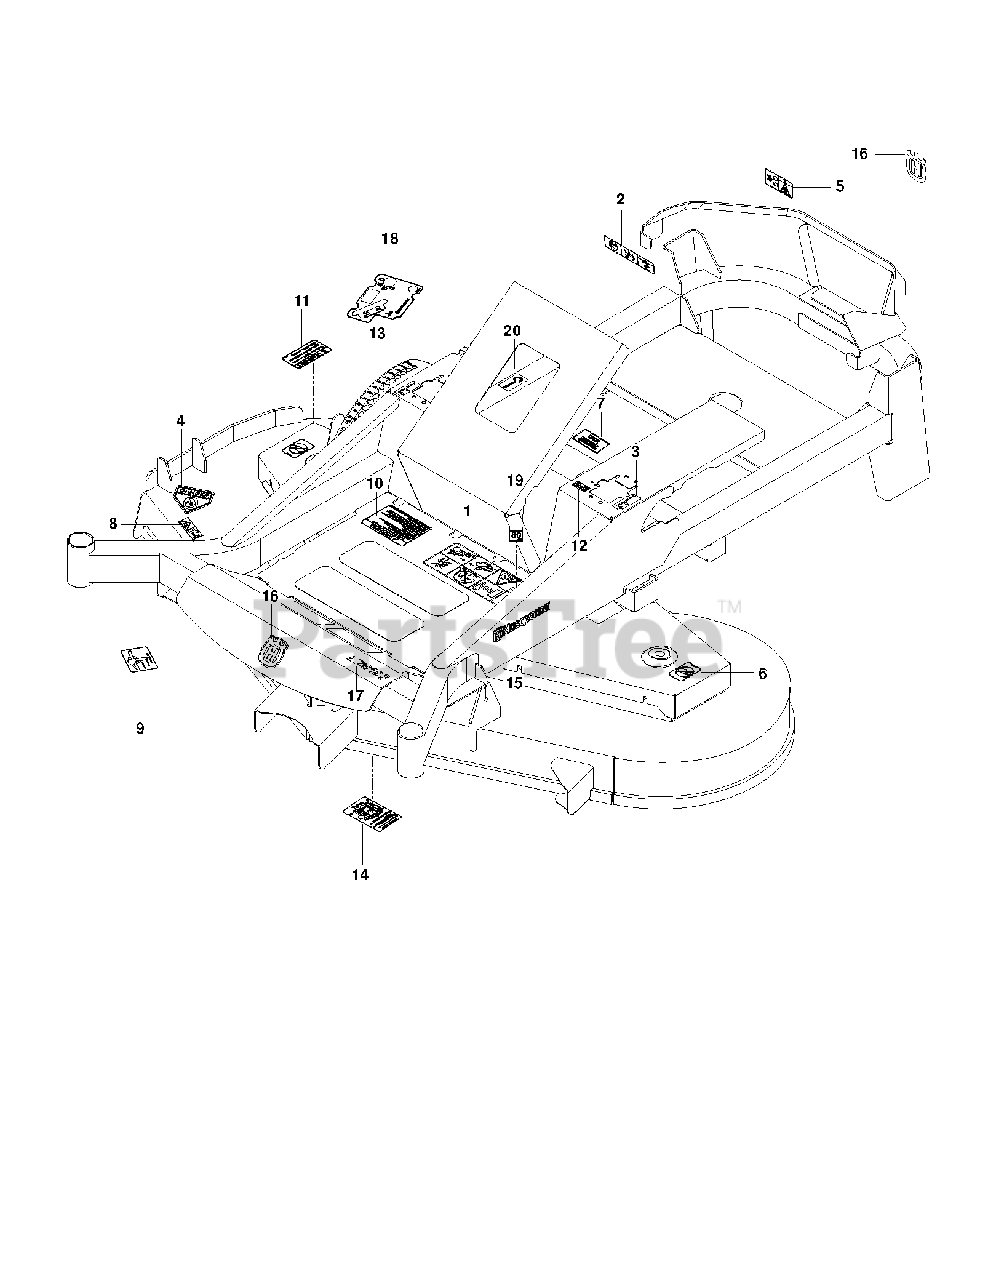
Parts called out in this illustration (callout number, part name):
1	DECAL, WARNING
2	EURO DECAL-BATTERY WARNIN6
3	DECAL, MOTION CONTROL
4	DECAL, CPSC
5	DECAL, BELT DRIVE
6	DECAL, NO STEP
7	HG_DECAL, ZT-3400
8	DECAL, EURO SEVERING
9	DECAL, BELT ROUTING
10	DECAL, WARNING
11	DECAL, CAUTION
12	DECAL, F.S.T.
13	DECAL, HEIGHT ADJUST
14	DECAL, SERVICE
15	RP.DECAL.BADGE.170MM.TEXTLOGO
16	DECAL.AUGER.HUSQ.CROWN.SNOW
17	DECAL, MZ6128
18	DECAL, CONSOLE HUS
19	DECAL 80 DBA
20	DECAL, ECM, AUSTRALIA
